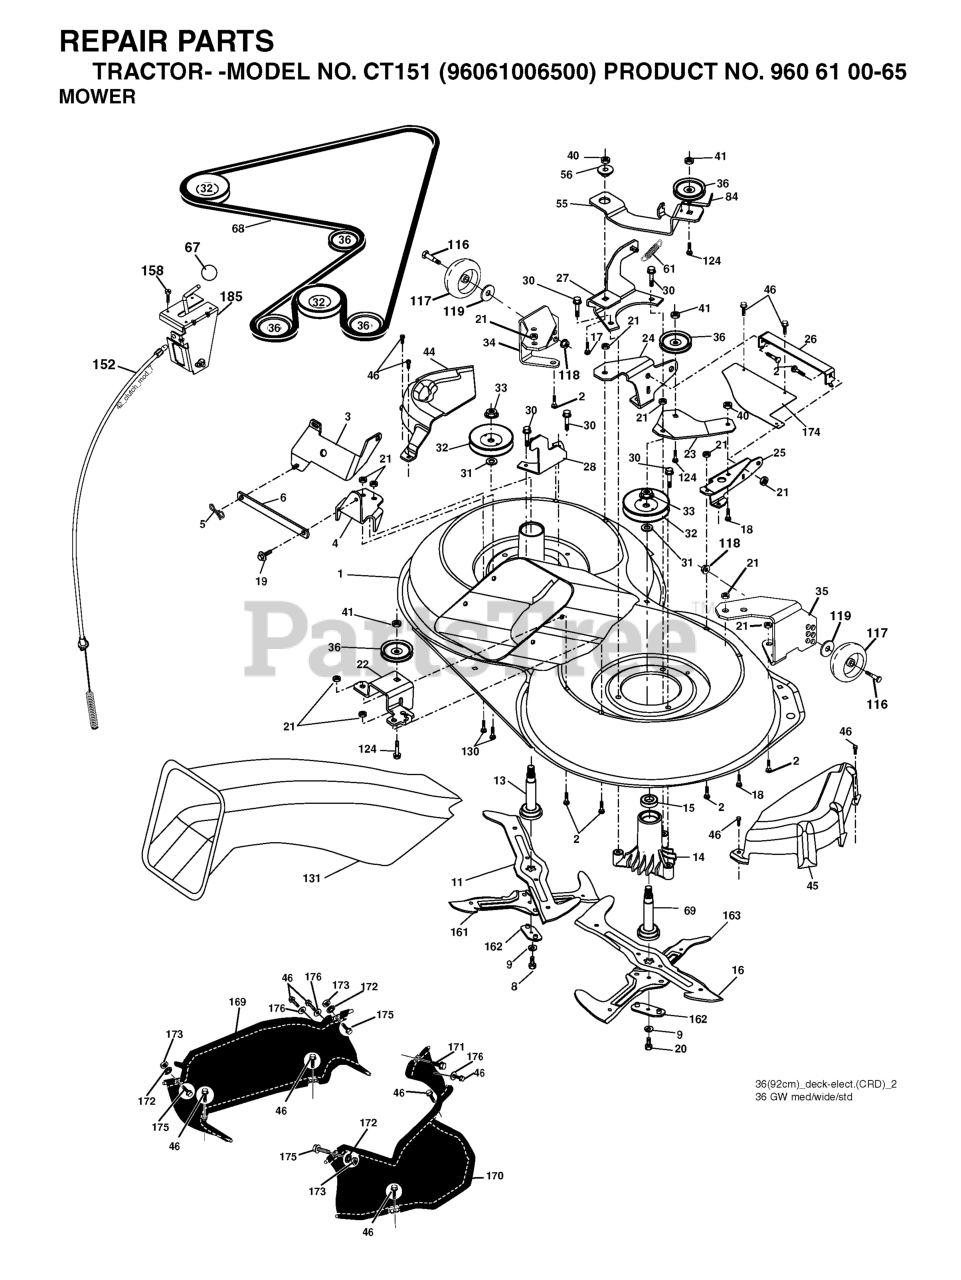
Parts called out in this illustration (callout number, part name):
2	RP BOLT 5/16-18 X3/4 ZN/YEL GR
5	RETAINER-SPRNG RB
6	BAR.SWAY.92.CRD
8	BOLT.3/8-24X1.25 GR8
9	LOCKWASHER
13	SHAFT ASM VENT
14	HOUSING.MANDREL.VENTED (MACHD)
17	BOLT.3/8-14X1.25
19	BOLT SHD 5/16-18
20	BOLT.3/8-24X1.25GR8. LHTHRD
21	LOCKNUT
26	SUPPORT
30	SCREW, WASHER HEAD
31	WASHER.SPACER.MANDREL
33	NUT.FLANGE.LOCK.TOP
36	PULLEY.IDLER.4.25
41	NUT LOCK FLG 3/8-16 UNC
45	COVER.MANDREL.RH.CRD
46	SCREW.1/4-20X5/8
55	ARM.IDLER.92 CRD.2006
56	SPACER.RETAINER.MOWER
61	SPRING
67	KNOB T (3/8 HOLE)
68	HEX-BELT
69	SHAFT.ASM.W/LWR.BRG.RH.THREAD
84	KEEPER, BELT IDLER
116	SHOULDER BOLT
117	RP WHEEL. GUAGE RALLY
118	LOCKNUT
119	WASHER.5/16.FLAT.STE.STD.
124	BOLT.3/8-16X1.50
130	BOLT.CARR.SQNK.5/16-18UNC.X3/4
131	CHUTE BAGGER
158	SCREW
169	COVER TERMINAL BATTERY
172	PUSH.NUT.ROUND.3/8.DIAM
173	NUT
175	BOLT D
185	HEAD ASM. CABLE CLUTCH
